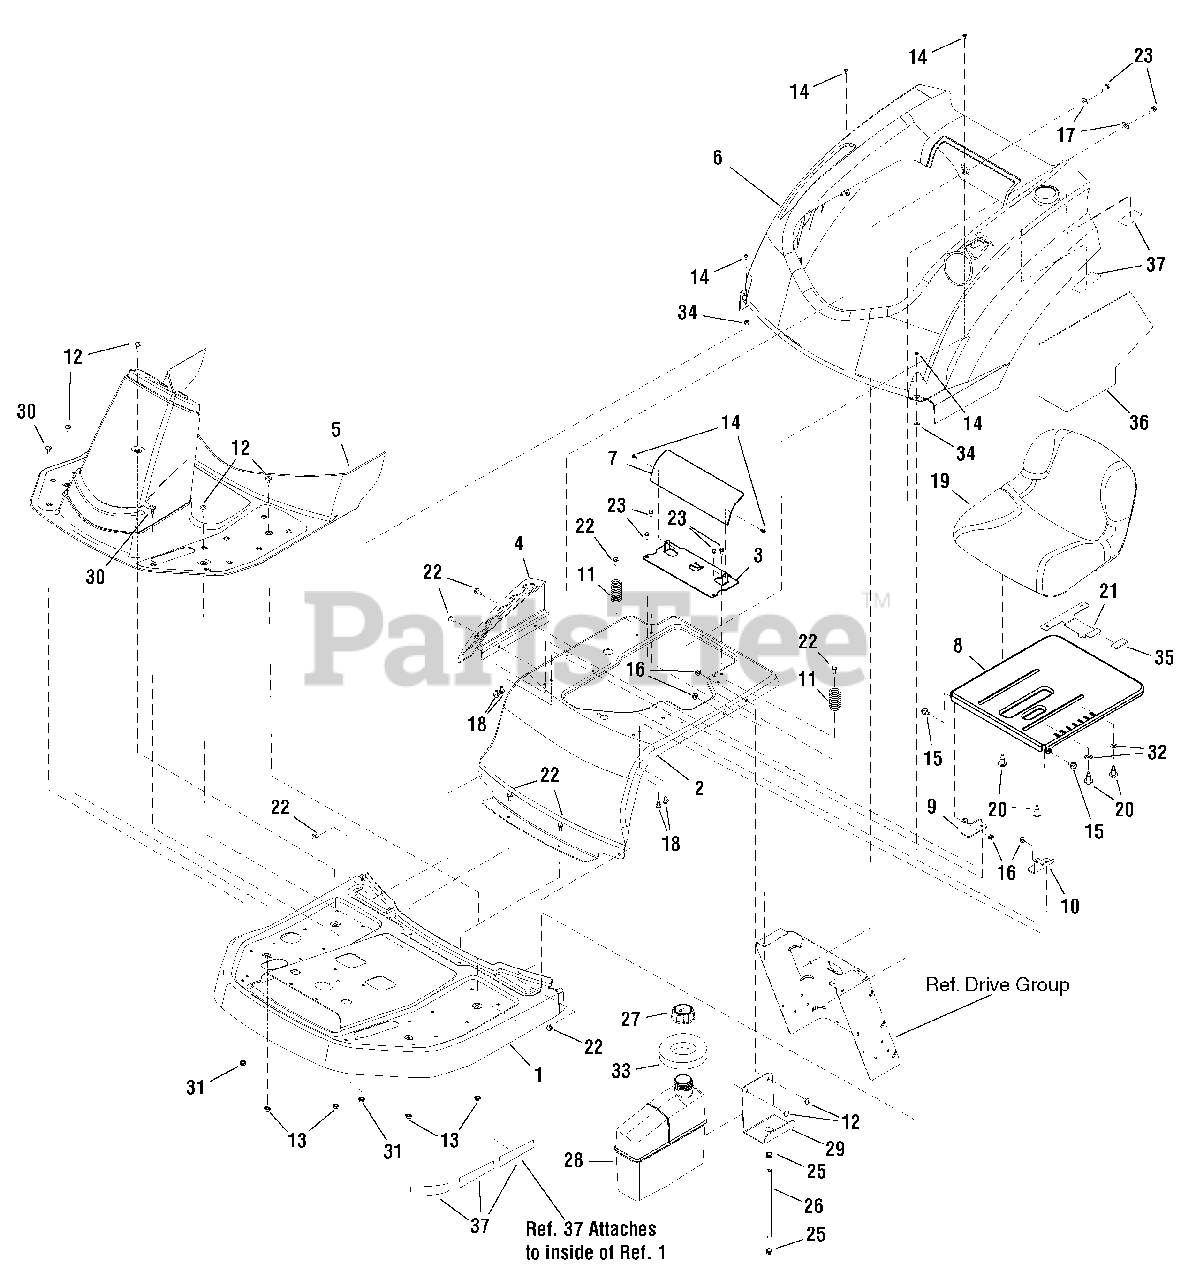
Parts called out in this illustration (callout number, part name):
1	FOOTREST
2	SEAT SUPPORT
3	COVER, Seat Support
4	DECK LIFT INDEX ASSY
5	FOOTREST, Plastic
6	BODY, Plastic
7	BATTERY COVER
8	BRACKET, Seat
9	SEAT SUPPORT, Bracket RH
10	SEAT SUPPORT, Bracket LH
11	SPRING, Seat
12	BOLT, Carriage, 5/16-18 x 5/8
13	NUT, Hex Flange, 5/16-18
14	SCREW, Shoulder #10-24
15	BOLT, Shoulder 5/16-18 x 5/8
16	NUT, Hex Flange Centerlock 5/16-18
17	WASHER, Flat, 3/4
18	SCREW, 5/16-18 x 0.50
19	SEAT
20	BOLT, Shoulder, 5/16-18 x 1.50
21	LEVER, Seat Adjust
22	CAPSCREW, 5/16-18 x 3/4
23	SCREW, Hex 1/4-20 x 5/8
24	BOLT, Carriage 5/16-18 x 5/8
25	CLAMP, Hose, Yellow
26	FUEL LINE
27	FUEL CAP
28	TANK, Fuel 1.6 Gallon.
29	BRACKET, Fuel Tank
30	BOLT, Carriage, 1/4-20 x 0.63
31	NUT, Keps Lock 1/4-20
32	WASHER, Flat, .81 X .550 X 16GA
33	RING, Foam
34	NUT, Flange Lock 1/4-20
35	GRIP, Seat Adjustment Lever
36	HEAT SHIELD
37	TAPE, Reflective
